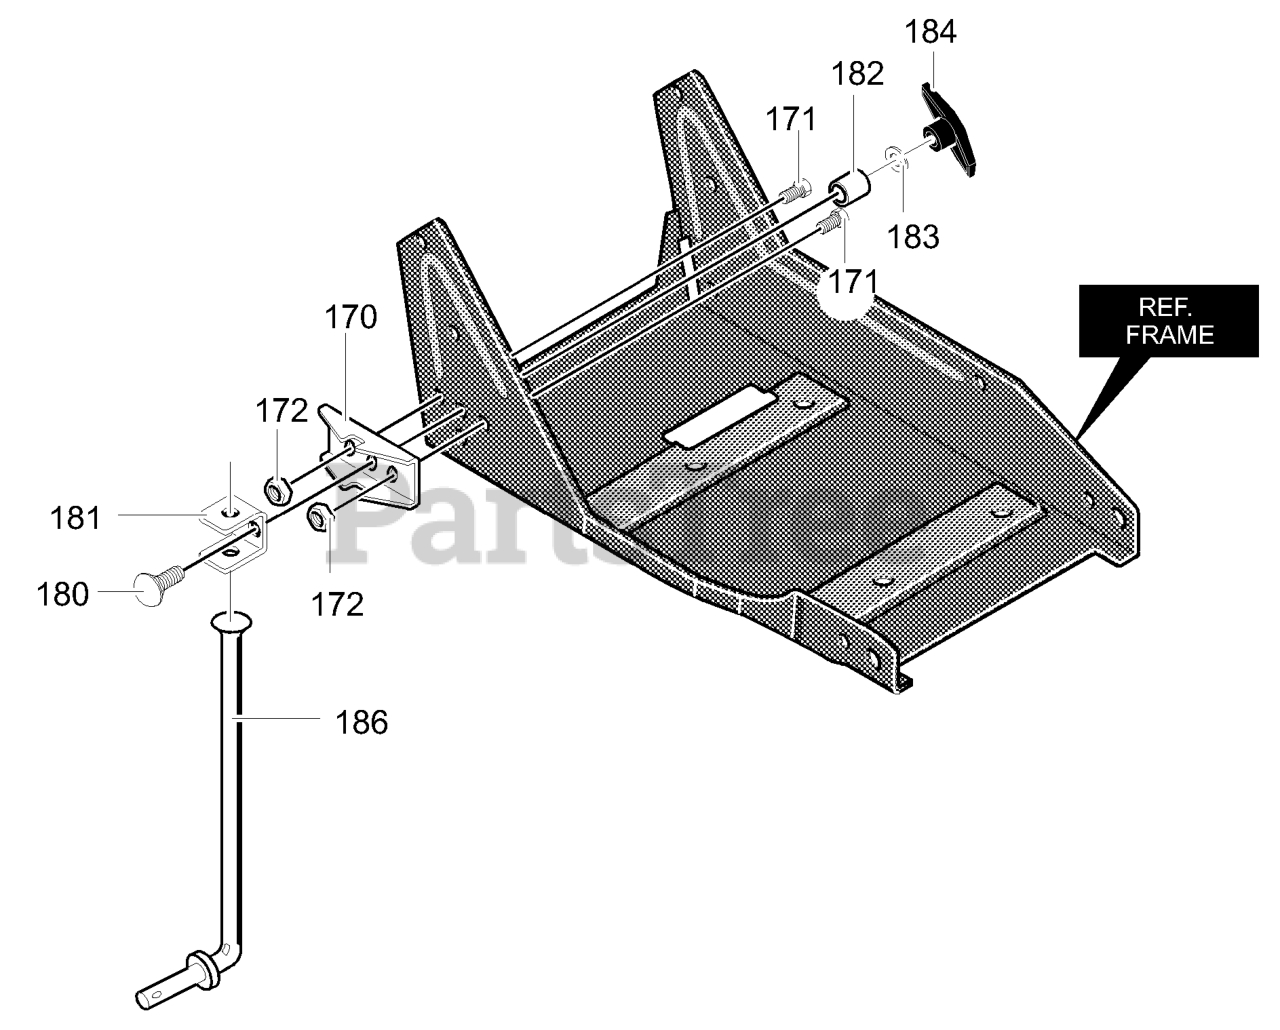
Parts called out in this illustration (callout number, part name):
170	Bracket, Curb Hop Mnt
171	Screw, 5/16-18 x 0.75
172	Nut, 5/16-18
180	Bolt, 5/16-18x2.00
181	Clevis
182	Spacer, Sleeve
183	Flatwasher
184	Knob, Wing 5/16-18
186	Rod, Wheel Support
